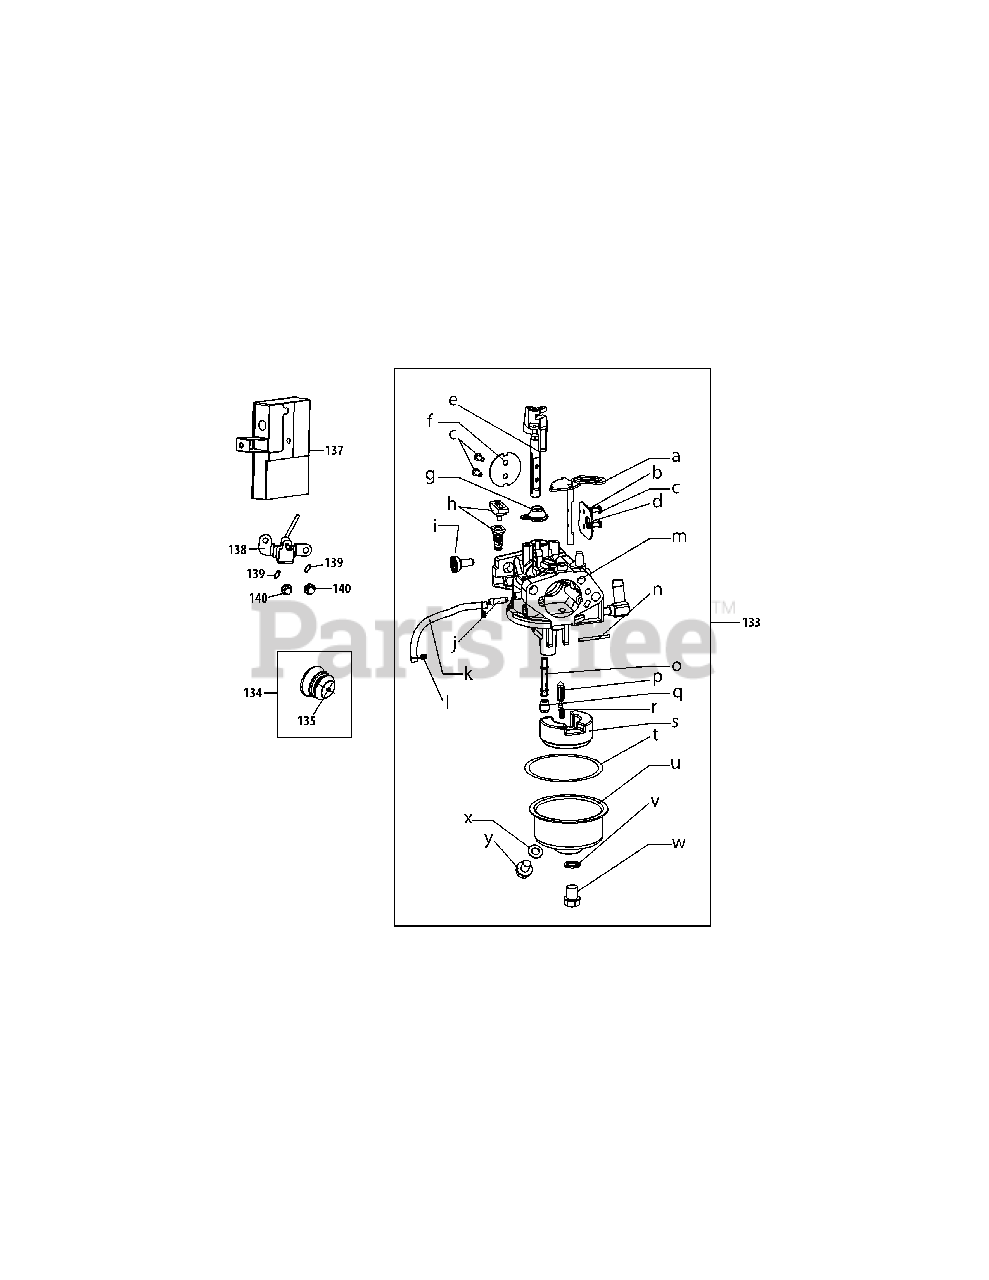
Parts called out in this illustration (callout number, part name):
133	Carburetor Ass’y
134	Primer Ass’y
135	Primer Bulb
137	Heater Box
138	Choke Control
139	Lock Washer
